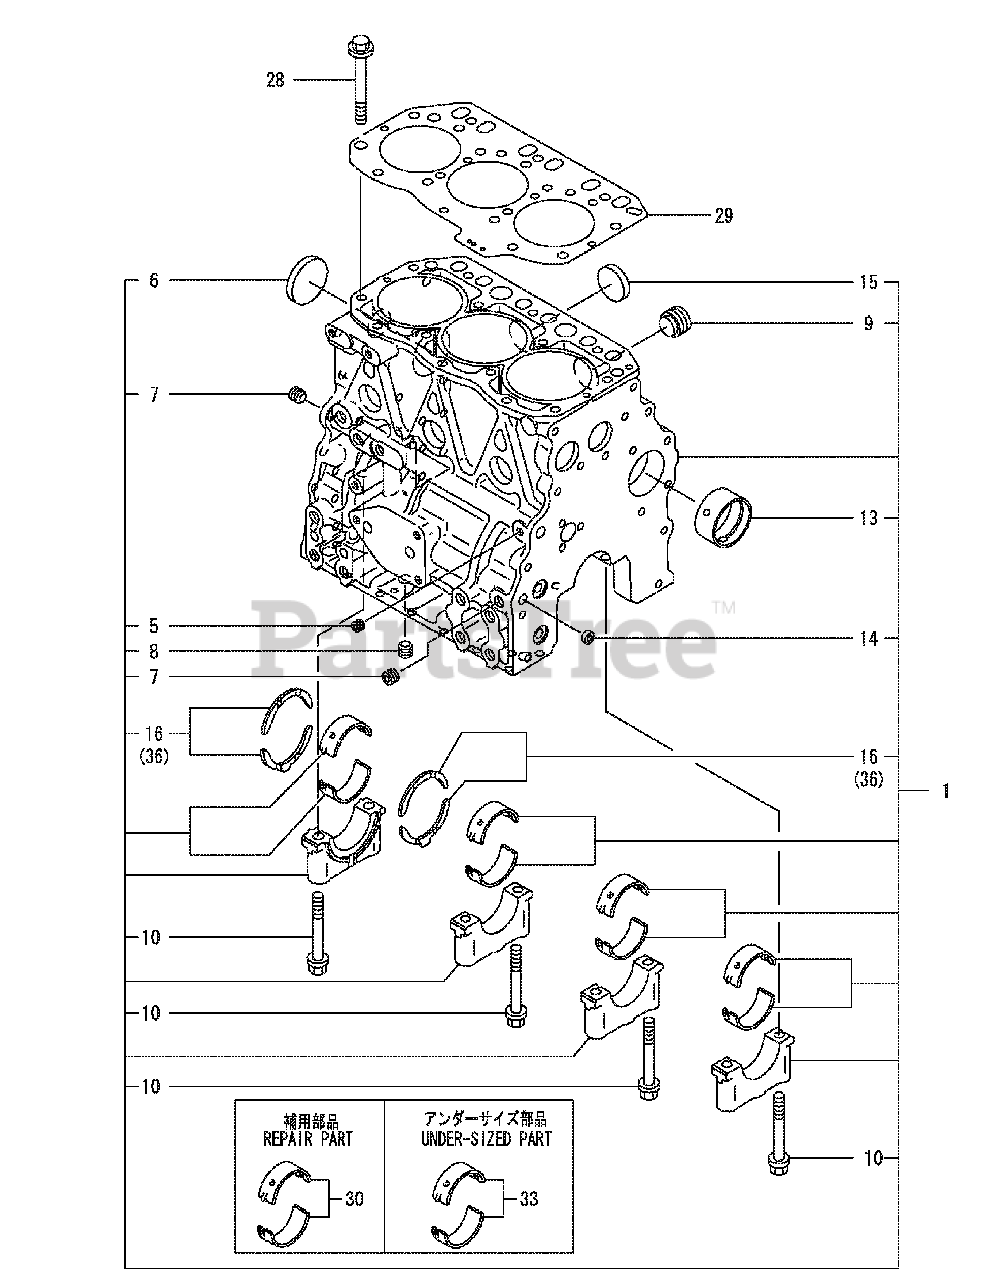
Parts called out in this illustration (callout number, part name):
1	Cylinder Block Assembly
10	Metal Cap Bolt
13	Camshaft Bushing
16	Thrust Bearing
28	Cylinder Head Bolt
30	Main Bearing Assembly
33	Main Bearing, .25
36	Thrust Bearing, .25
